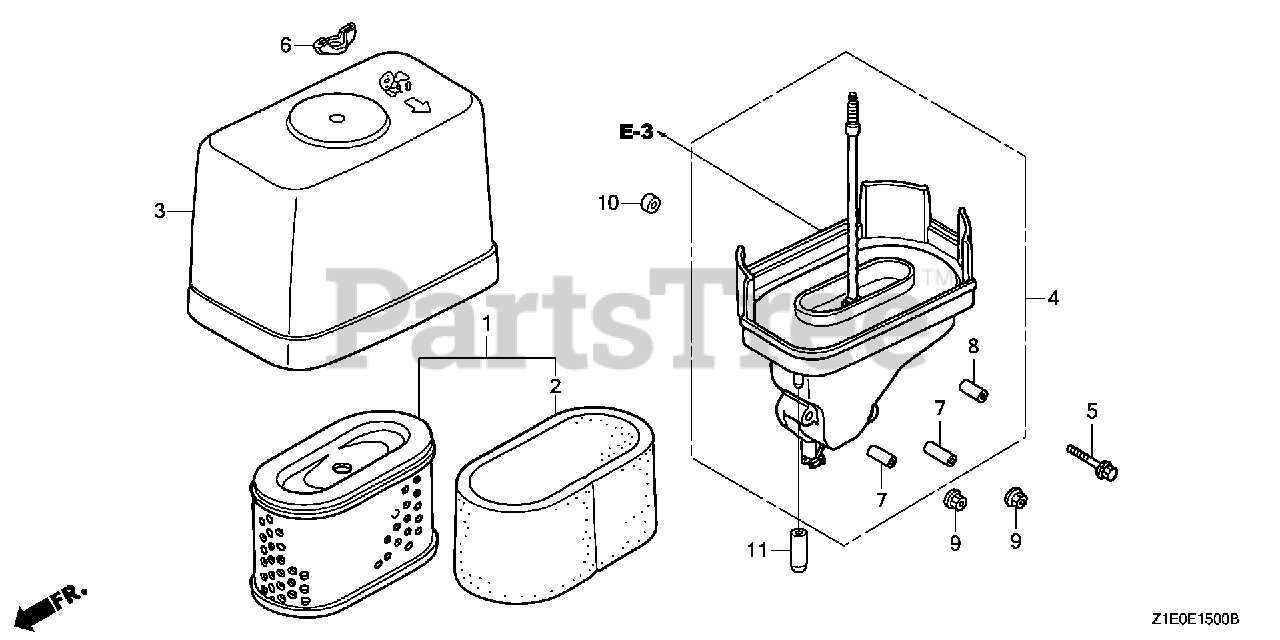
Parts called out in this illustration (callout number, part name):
1	ELEMENT, AIR CLEANER
3	COVER, AIR CLEANER
4	ELBOW, AIR CLEANER
5	BOLT, FLANGE (6X45)
6	WINGNUT, TOOL BOX SETTING
7	COLLAR, AIR CLEANER
8	COLLAR, AIR CLEANER
9	NUT, FLANGE (6MM)
10	SPACER, AIR CLEANER ELBOW
11	CAP, SEALING
